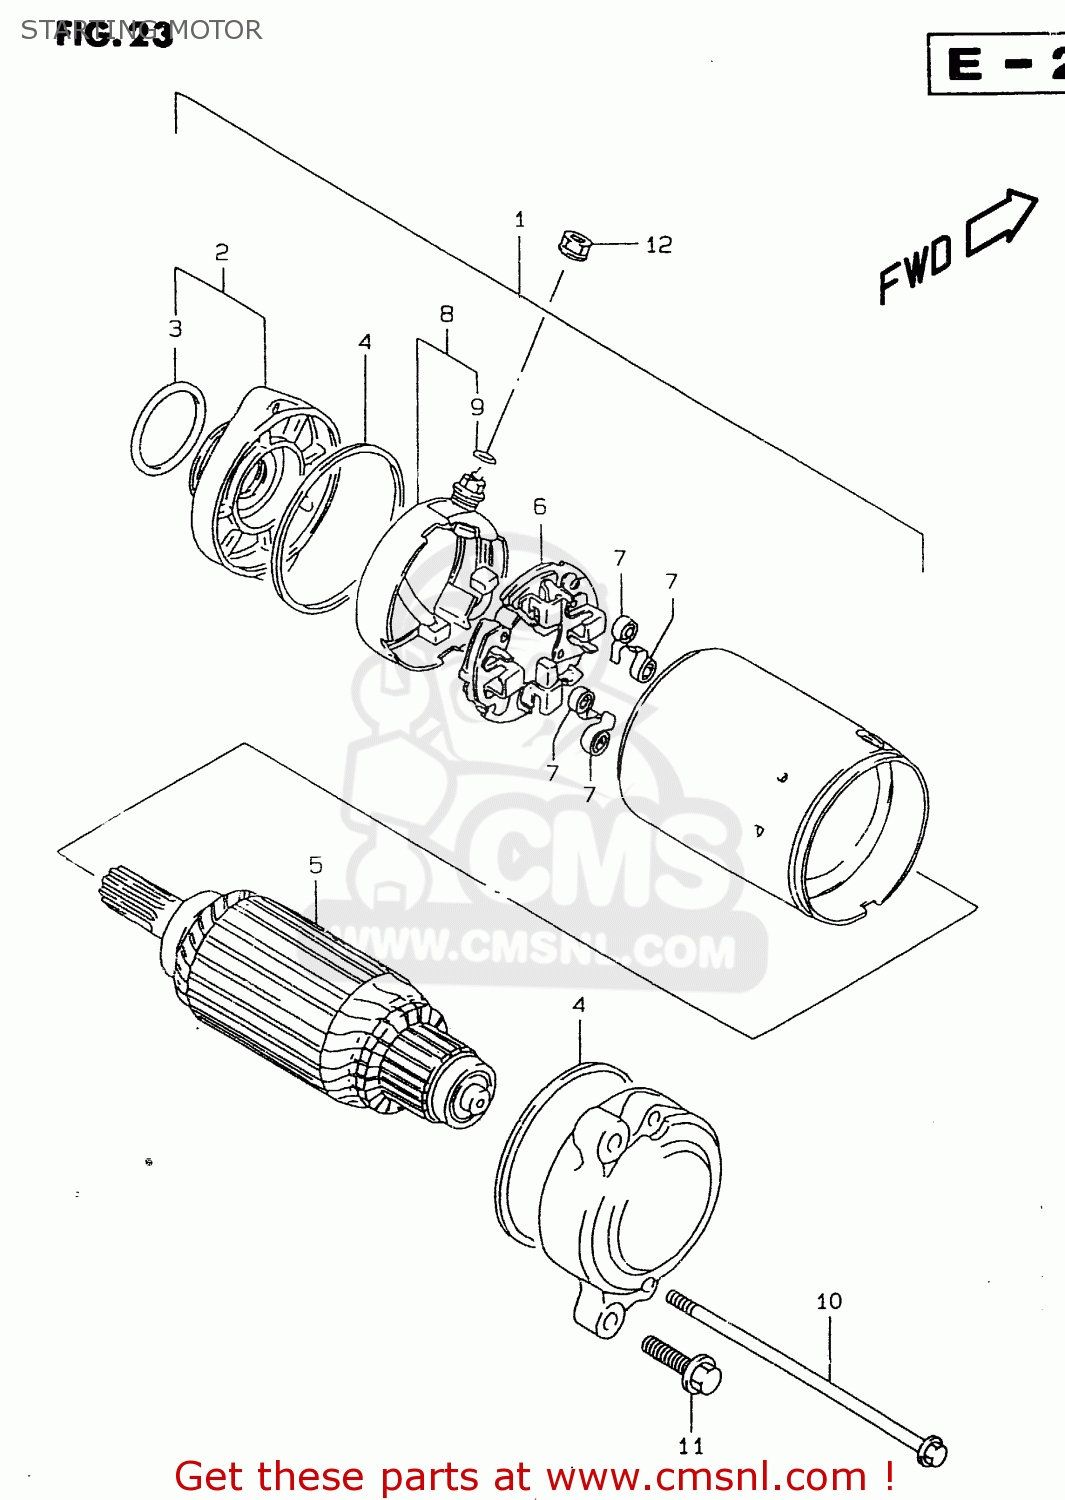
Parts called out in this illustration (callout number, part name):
1	MOTOR ASSY,STARTING
2	BRACKET SET
3	O-RING
4	SQUARE RING
5	ARMATURE
6	HOLDER SET,BRUSH
7	SPRING,BRUSH
8	TERMINAL SET,BRUSH
9	O RING
10	BOLT
11	BOLT
12	NUT
